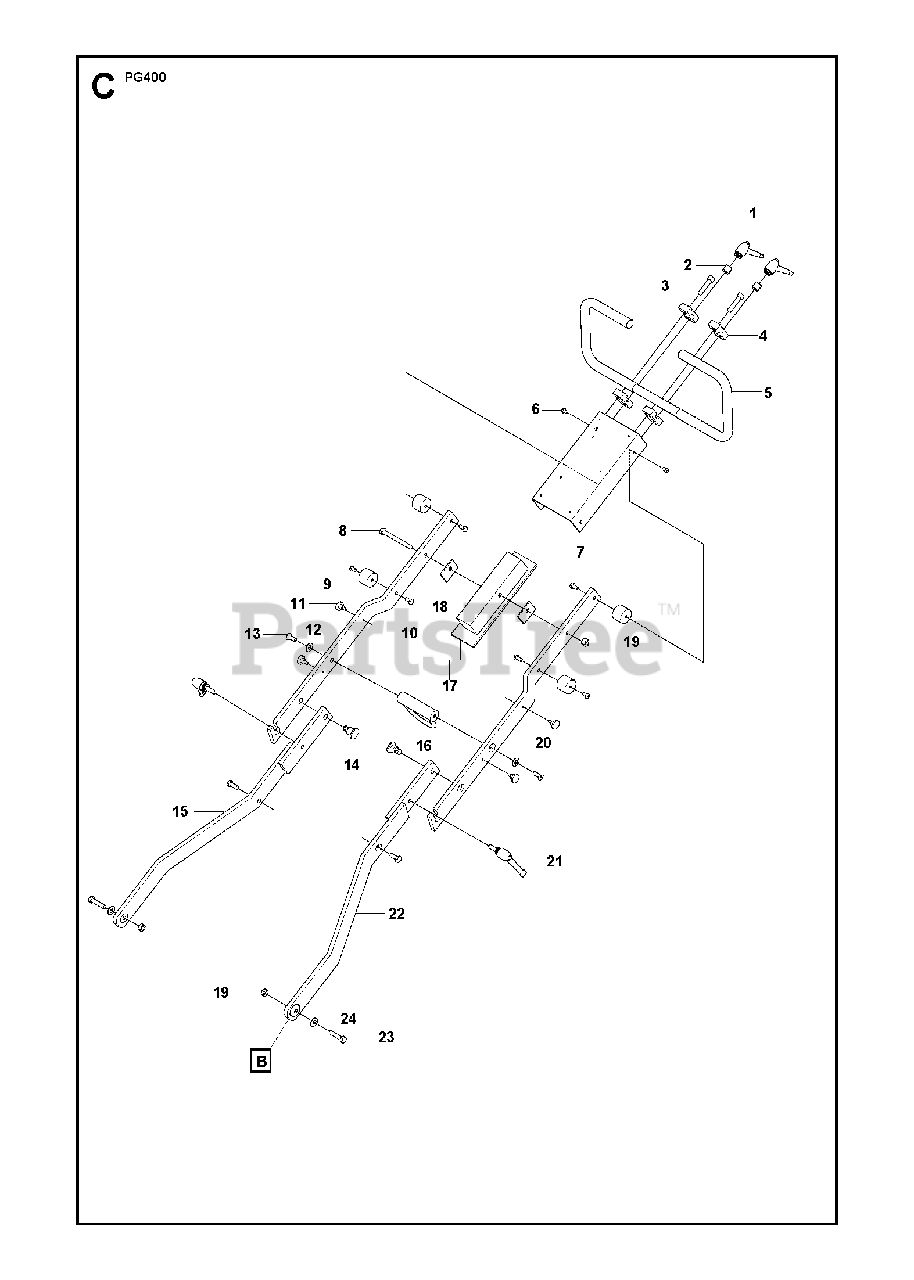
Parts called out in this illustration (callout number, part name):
10	SCREW EHHM
19	HEXAGON LOCKING NUT
24	WASHER
